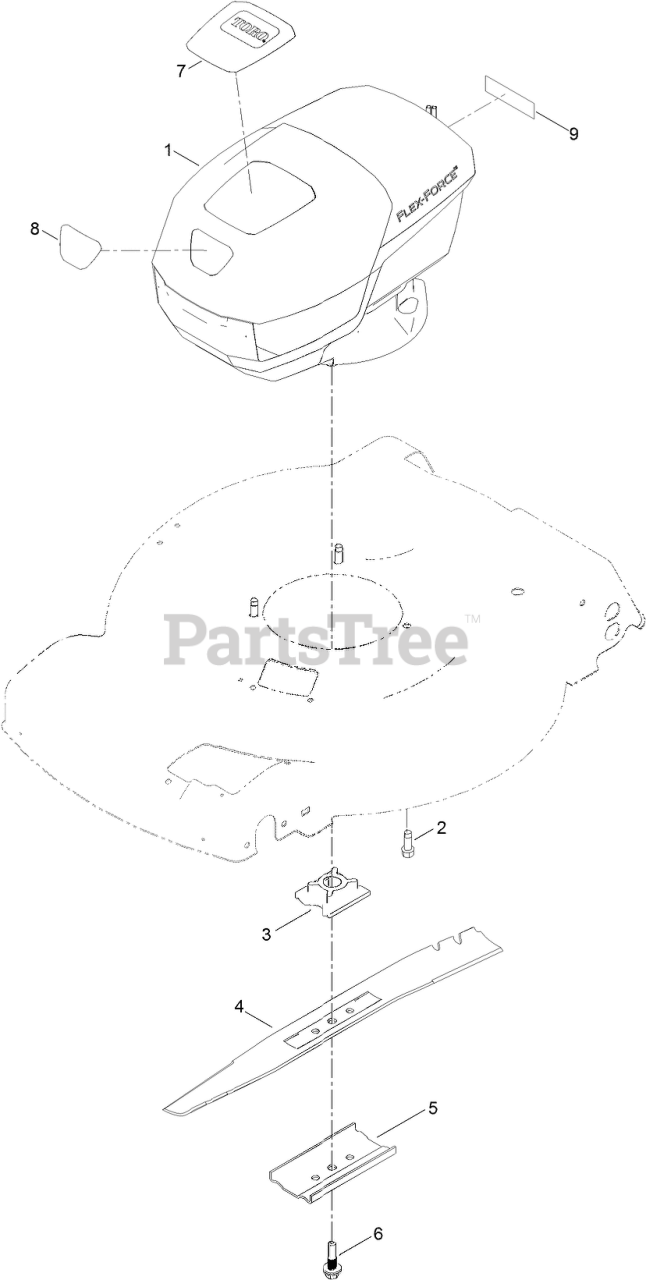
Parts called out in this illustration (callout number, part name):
1	MOTOR MODULE (60V)
2	SCREW-TAPTITE
3	RETAINER-BLADE
5	SUPPORT-BLADE
6	BOLT-BLADE
7	DECAL-HOOD, TOP
8	DECAL-HOOD, FRONT
9	DECAL-WARNING
